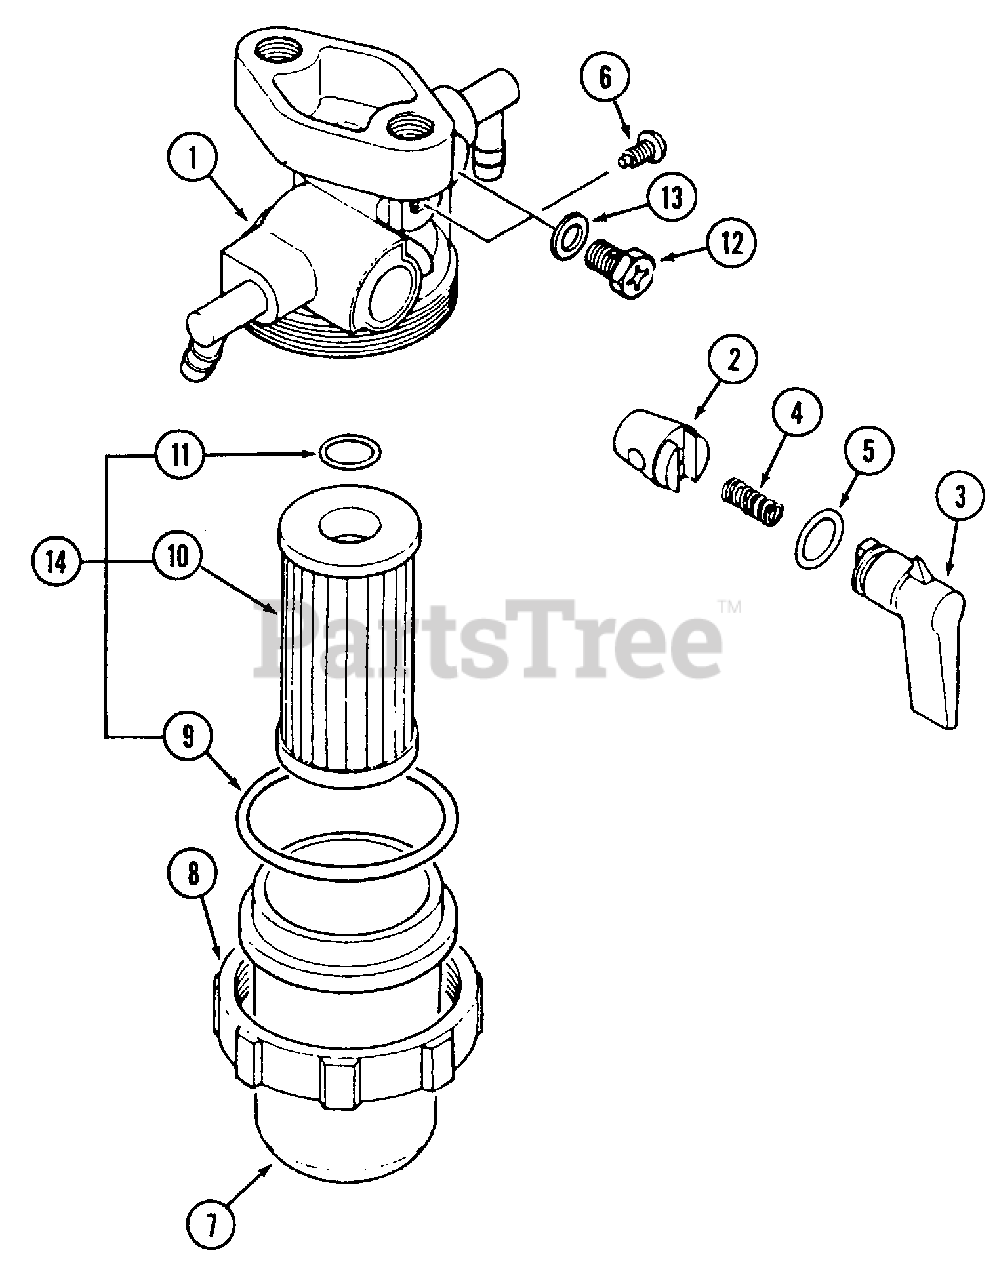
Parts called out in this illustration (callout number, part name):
1	Body Sub Ass'y.
2	Valve
4	Spring, Valve
5	O-Ring, Valve
7	Cup, Filter
9	O-Ring, Filter Cup
10	Element
11	O-Ring, Element
12	Screw, Air Vent
14	Service Kit, Fuel Filter
